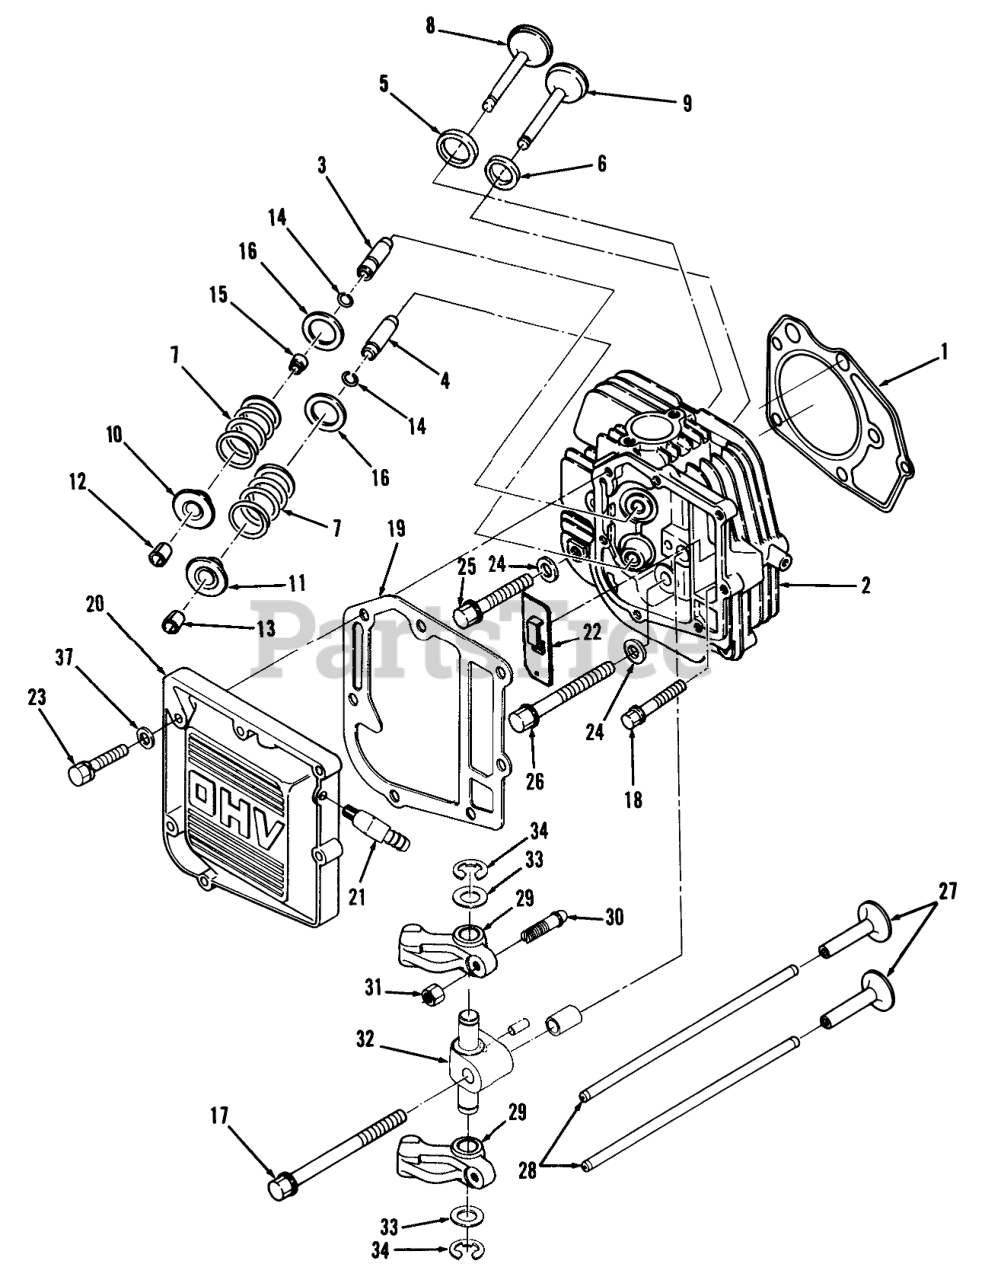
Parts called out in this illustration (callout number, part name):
1	GSKT-CYL HEAD
2	Cylinder Head Assembly (Incl. Ref. #3-16)
3	GUIDE-INTAKE VALVE
4	GUIDE-EXH VALVE
5	Seat-Intake Valve
6	Seat-Exhaust Valve
7	SPRING-VALVE
8	VALVE-INTAKE MKD IN
9	VALVE-EXHAUST MKD EX
10	RETAINER-VLV SPG IN
11	RETAINER-VLV SPG EX
12	Lock-Intake
13	LOCK-VALVE EXHAUST
14	RING-VALVE GUIDE
15	Seal-Intake
16	WASHER-VALVE SPRING
17	BLT-CYL HD M10X125MM
18	BLT-CYL HD M8X50MM
19	Seal
20	Cover-Valve
21	ELBOW-90 DEGREES
22	BREATHER
23	SCRW-CP SH M6X25MM
24	WASHER-FLAT M10
25	BLT-CYL HD M10X66MM
26	BLT-CYL HD M10X86MM
27	TAPPET
28	ROD-PUSH
29	Rocker Arm Assembly (Incl. Ref. #30 & 31)
30	SCRW-LASH ADJUSTING
31	NUT-LASH ADJUSTING
32	SHAFT-ROCKER ARM
33	Rocker Arm Washer
34	CLIP-RETAINER
35	PIN-DOWEL
36	PIN-DOWEL HOLLOW
37	WASHER-FLAT
